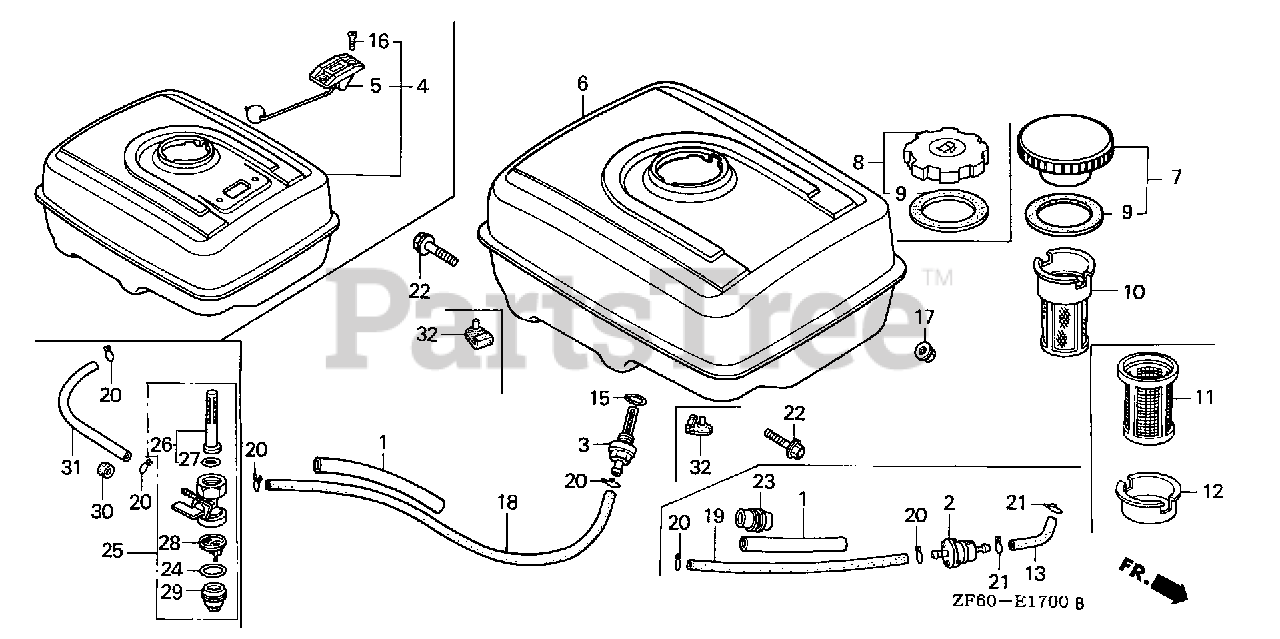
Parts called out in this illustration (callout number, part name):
1	RUBBER, SUPPORTER (107MM)
3	JOINT, FUEL TANK (NOT AVAILABLE)
3	JOINT, FUEL TANK
6	TANK, FUEL *NH31* (MCKINLEY WHITE)
6	TANK, FUEL *NH1* (BLACK)
7	CAP, FUEL FILLER
8	CAP, FUEL FILLER (BLACK)
9	GASKET, FUEL FILLER CAP (39X58X3)
10	FILTER, FUEL
11	FILTER, FUEL
12	HOLDER, FUEL FILTER
15	O-RING (14MM) (ARAI)
15	O-RING (14MM) (NOK)
17	NUT, FLANGE (8MM)
18	BULK HOSE, FUEL (4.5X3000) (4.5X235)
20	CLIP, TUBE (B8)
22	BOLT, FLANGE (8X25)
